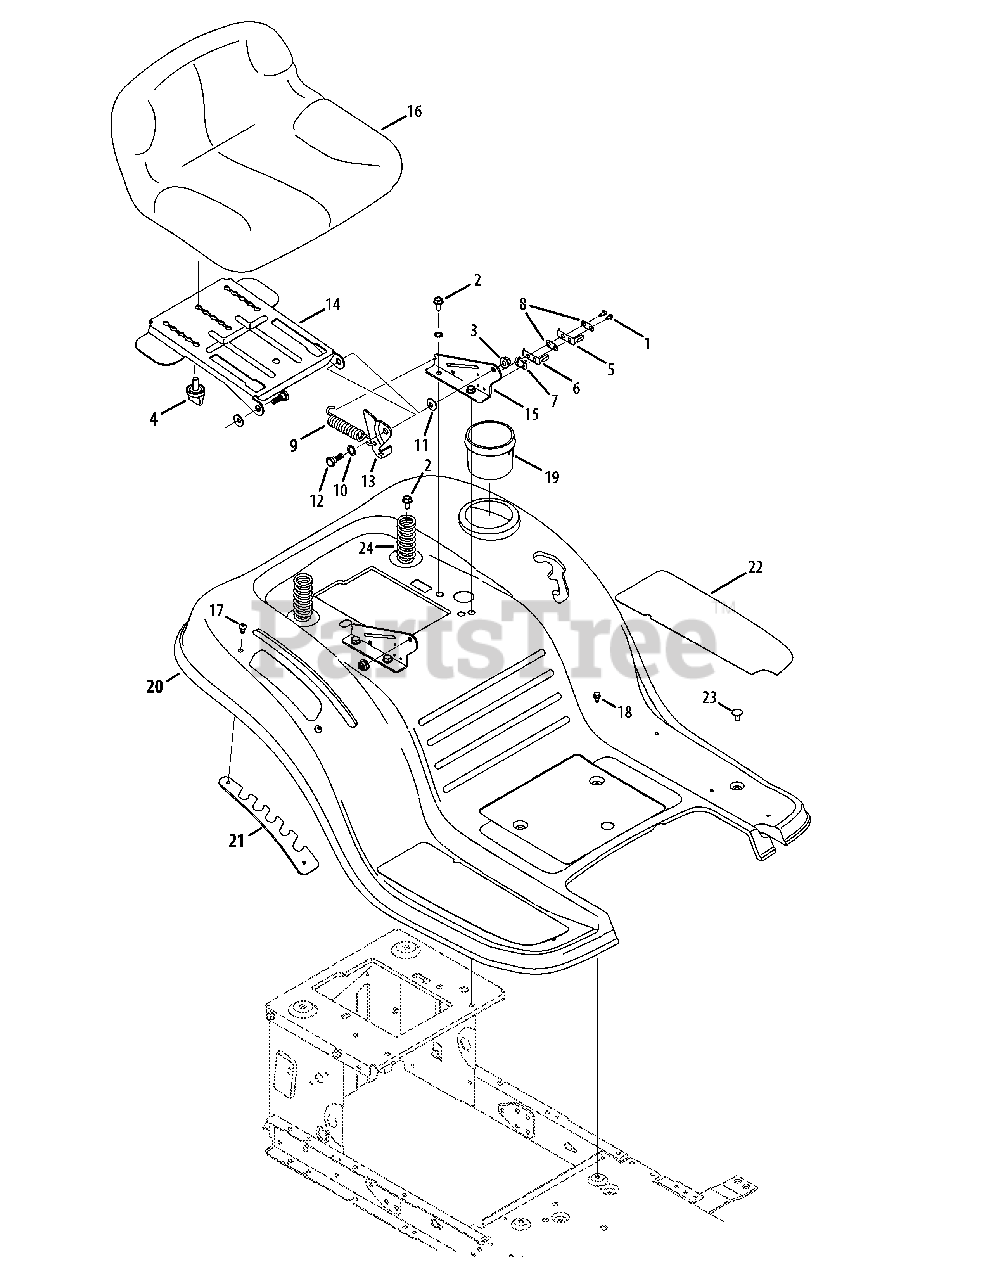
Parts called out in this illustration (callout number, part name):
1	Screw, 8-18 x .500
2	Screw, 5/16-18 x .750
3	Flange Lock Nut, 5/16-18
4	Knob, 3/8-16 x .875
5	Outer Seat Spring
6	Inner Seat Spring
7	Insulator Boss Plate
8	Insulator Plate
9	Extension Spring
10	Flat Washer, .510 x .750 x .033
11	Flat Washer, .340 x .872 x .060
12	Shoulder Screw, 5/16-18 x .437 x .268
13	Lift Seat Bracket
14	Seat Pivot Bracket
15	Seat Mounting Bracket
16	Low Back Seat
17	Screw, 1/4-20 x .500
18	Screw Pan Torx Head, 1/4-20 x .500
19	Cup Holder
20	Fender
21	Lift Adjuster Bracket
22	Abrasive Foot Pad, LH
22	Abrasive Foot Pad, RH
23	Carriage Screw, .62: 1/4-20
24	Spring, Compress., 1.28 x 3.125
